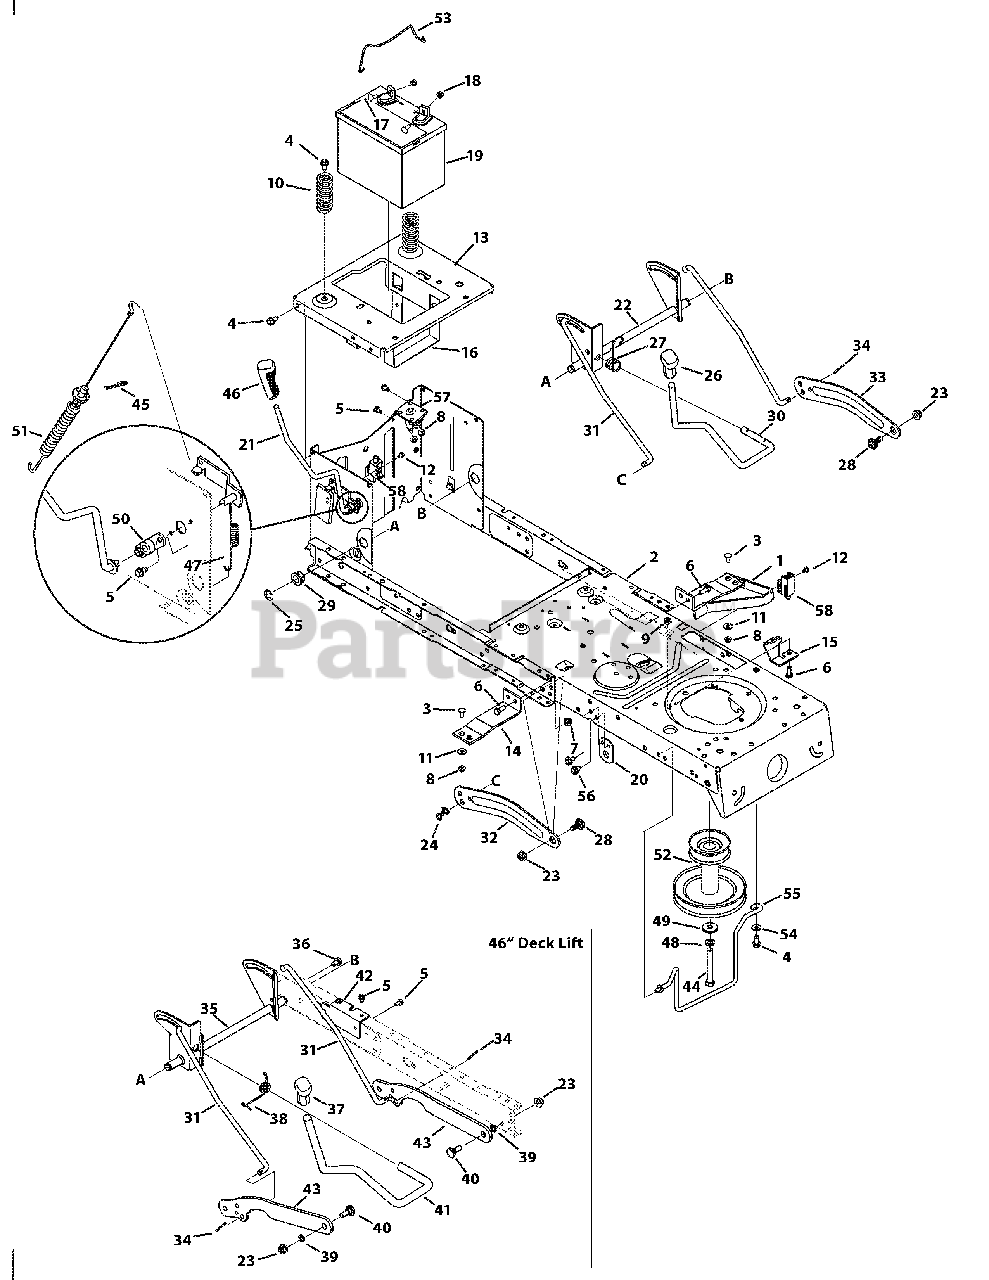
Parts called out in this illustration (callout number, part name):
1	Support Bracket
2	Frame Assembly - Powder Black
2	Frame Assembly - Green
2	Frame Assembly - Black Jack
2	Frame Assembly - Red
3	Screw Carriage, 1/4-20 x .62
4	Screw 5/16-18 x .750
5	Screw, 1/4-20 x .500
6	Hex Screw, 5/16-18 x .75
7	Flangelock Nut, 5/16-18
8	Flangelock Nut, 1/4-20
9	Hexlock Nut, 5/16-18
10	Compression Spacer, 1.28 x 3.125
11	Flat Washer, .28 x .74 x .063
12	Shoulder Spacer, 10-32 x .500
13	Seat Frame Bracket
14	Runningboard Bracket
15	Support Frame Bracket
16	Battery Bracket
17	Hex Head Flange, 1/4-20 x .75
18	Sems Nut, 1/4-20
19	245 CCA Battery
20	Support Bracket
21	PTO Handle Assembly
22	Lift Assembly, 38/42"
23	Flangelock Nut, 3/8-16
24	Bow-tie Cotter Pin
25	E Ring
26	Handle Grip, 1/2
27	Torsion Spring
28	Shoulder Bolt, 3/8-16 x .625 x .175
29	Hex Flange Bearing
30	Deck Lift Handle
31	Lift Rod
32	38/42" Lift Arm, RH
33	38/42" Lift Arm, LH
34	Cotter Pin, 1/8 x 1.0
35	Lift Assembly, 46"
36	Screw, 5/16-18 x .625
37	Handle Grip, 5/8
38	Torsion Spring Handle, 46"
39	Flat Washer, .385 x .62 x .063
40	Shoulder Bolt, 3/8-16 x .500 x .270
41	46" Lift Handle
42	Frame Brace Bracket
43	Lift Deck Link
44	Hex Screw, 7/16-20 x 2.75, 46"
44	Hex Screw, 7/16-20 x 3.25, 38/42"
45	Click Pin, .092 x 1.64
46	Handle Grip, 3/8
47	PTO Spring Extension
48	Regular Duty Washer Lock, 7/16
49	Flat Washer, .450 x 1.250 x .164
50	PTO Bearing
51	Deck Engage Cable
52	Engine Pulley, 3.39 x 6.12, 46"
52	Engine Pulley, 3.39 x 6.12, 38/42"
53	Battery Hold Down Rod
54	Flat Washer, .406 x .875 x .059
55	38" Belt Keeper
55	42" Belt Keeper
55	46" Belt Keeper
56	Screw, 5/16-18.0 x .625
57	12V Solenoid
58	Switch Interlock
